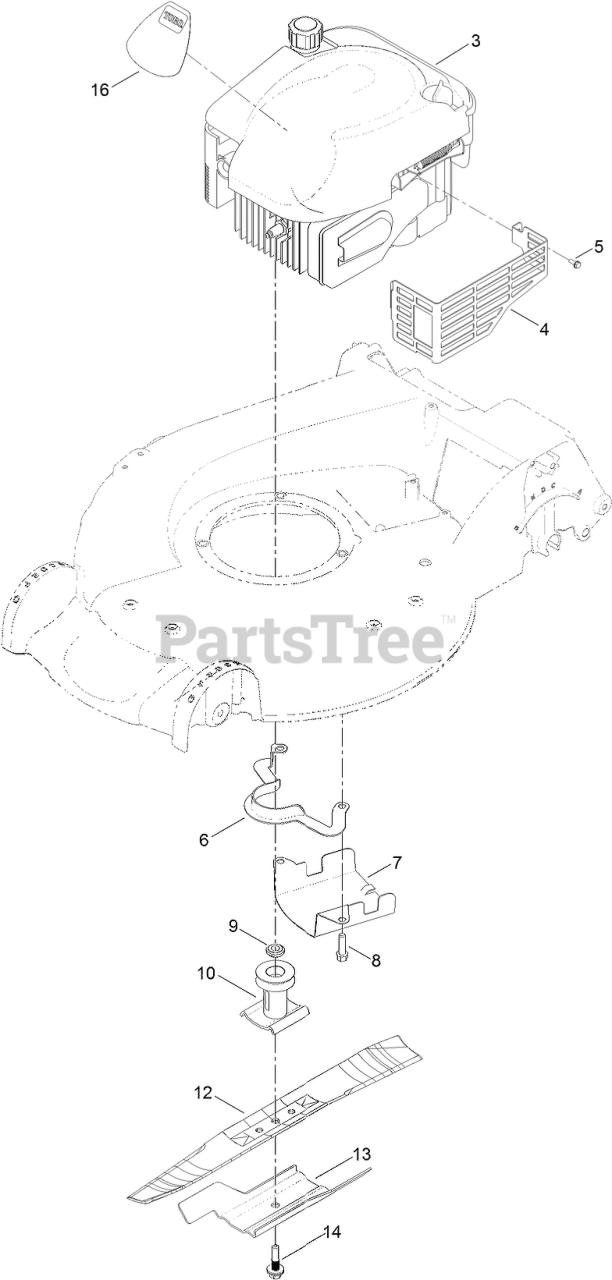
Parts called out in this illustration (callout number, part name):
4	SHIELD-MUFFLER
5	SCREW-TAPTITE
6	GUIDE-BELT
7	SHIELD-GRASS
8	SCREW-TAPTITE
9	Spacer-Driver
10	DRIVER-BLADE
12	BLADE-RECYCLING
13	Accelerator-Blade
14	BOLT-BLADE
16	DECAL-SHROUD
